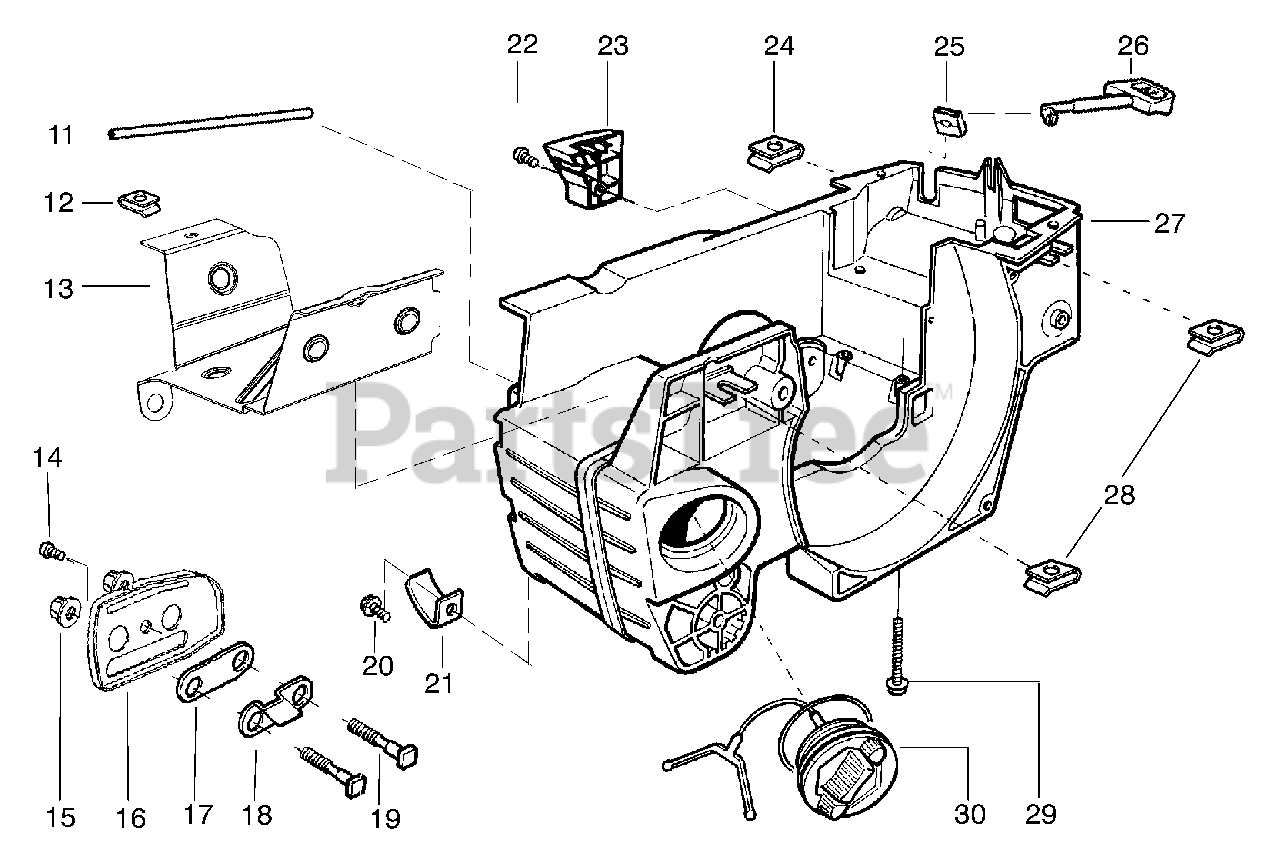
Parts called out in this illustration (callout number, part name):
11	Tube-Oil Vent
12	Clip-Retainer
13	Shield-Heat
14	Screw
18	Plate-Bar Stud
21	Chain Catcher
24	Nut-Type "U" Speed
26	Lever-Choke
27	Kit - Chassis Ass'y.
28	Nut-Type "U" Speed
30	Assy.- Oil Tank Cap
